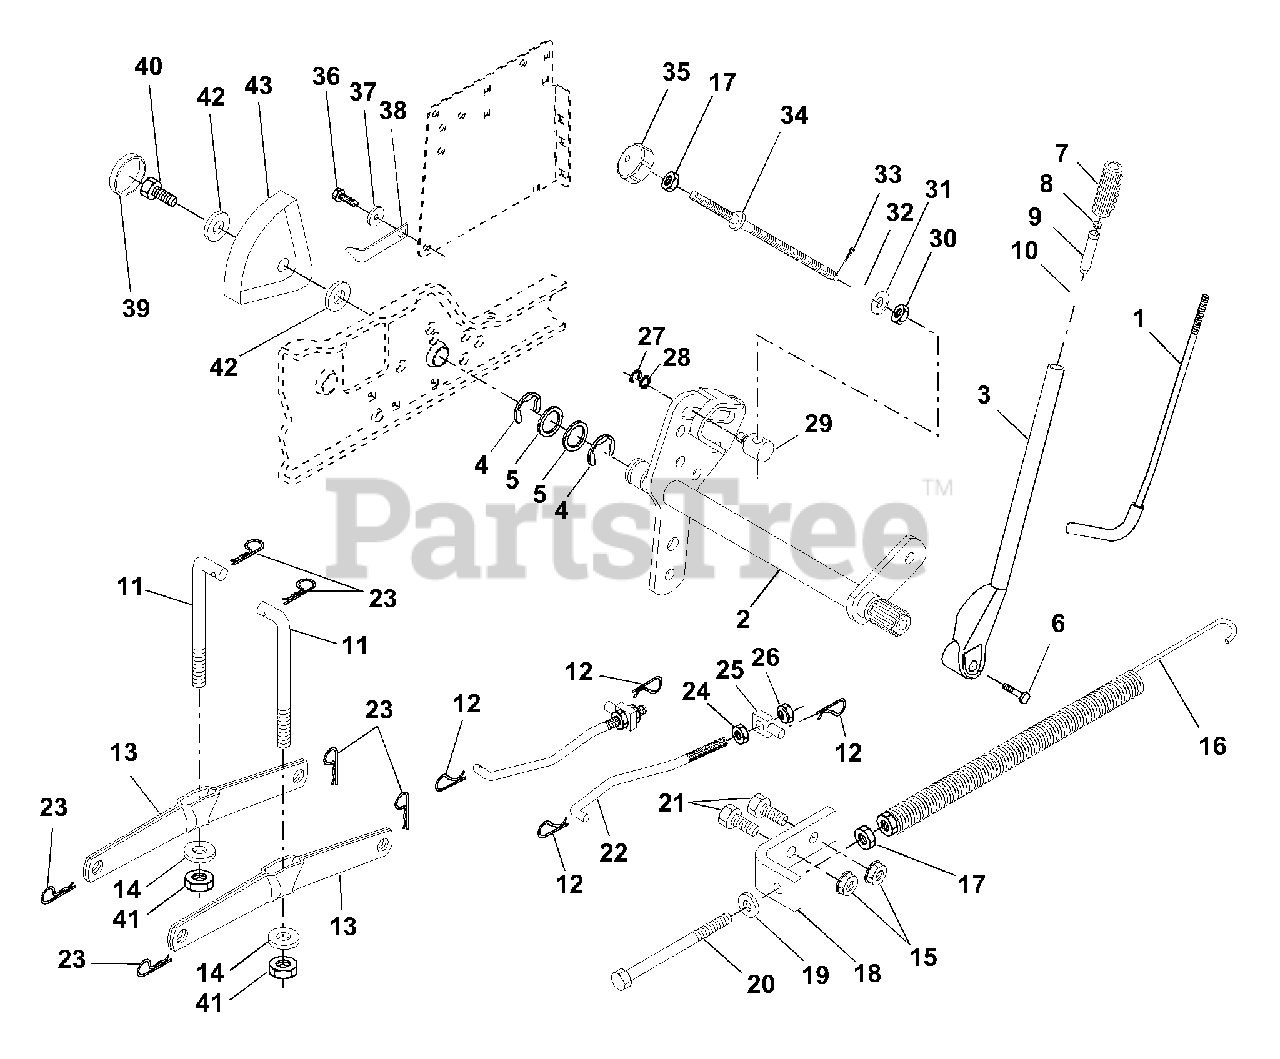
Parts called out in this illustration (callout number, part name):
1	Rod Asm., Lever
2	Shaft Asm., Lift Vgt
3	Lever Asm., Lift Rh
4	E-Ring Truarc #5133-87
5	Washer 29/32 x 1-1/4 x 16 Ga.
6	Bolt, Fin Hex 3/8-16 x 1-1/2
7	Grip, Handle Fluted
8	Button, Plunger
9	Plunger, Lever Lift
10	Spring 2-1/8"
11	Link Lift
12	Retainer, Spring
13	Arm, Suspension Vgt
14	Bearing
15	Nut, Crownlock 3/8-16 Unc
16	Spring Asm., Assist Lift
17	Nut, Hex Jam 3/8-16 Unc
18	Bracket, Spring Assist
19	Washer 13/32 x 13/16 x 16 Ga.
20	Bolt, Adjust Spring Assist
21	Bolt, Fin Hex 3/8-16 x 1
22	Link, Front
23	Retainer, Spring
24	Nut, Jam Hex 1/2-13 Unc
25	Trunnion
26	Nut, Lock W/Wsh 1/2-13 Unc
27	Ring, Klip #T5304-37
28	Washer 15/32 x 3/4 x 16 Ga.
29	Trunnion, Dp Stop Dbl Thds Plt
30	Nut, Special
31	Washer 13/32 x 5/8 x 16 Ga.
32	Spring, Compression Inf Hgt
33	Pin, Cotter 3/32 x 1/2
34	Rod, Adj Lift
35	Knob, Inf 3/8-16 Unc
36	Screw, Thdrol 3/8-16 x 3/4
37	Washer, Nylon
38	Pointer, Pnt Height Indicator
39	Plug, Hole
40	Screw, Thdrol 5/16-18 x 3/4 TYT
41	Nut, Crownlock 3/8-24
42	Washer 11/32 x 1-1/2 x 10 Ga.
43	Scale, Indicator Height
